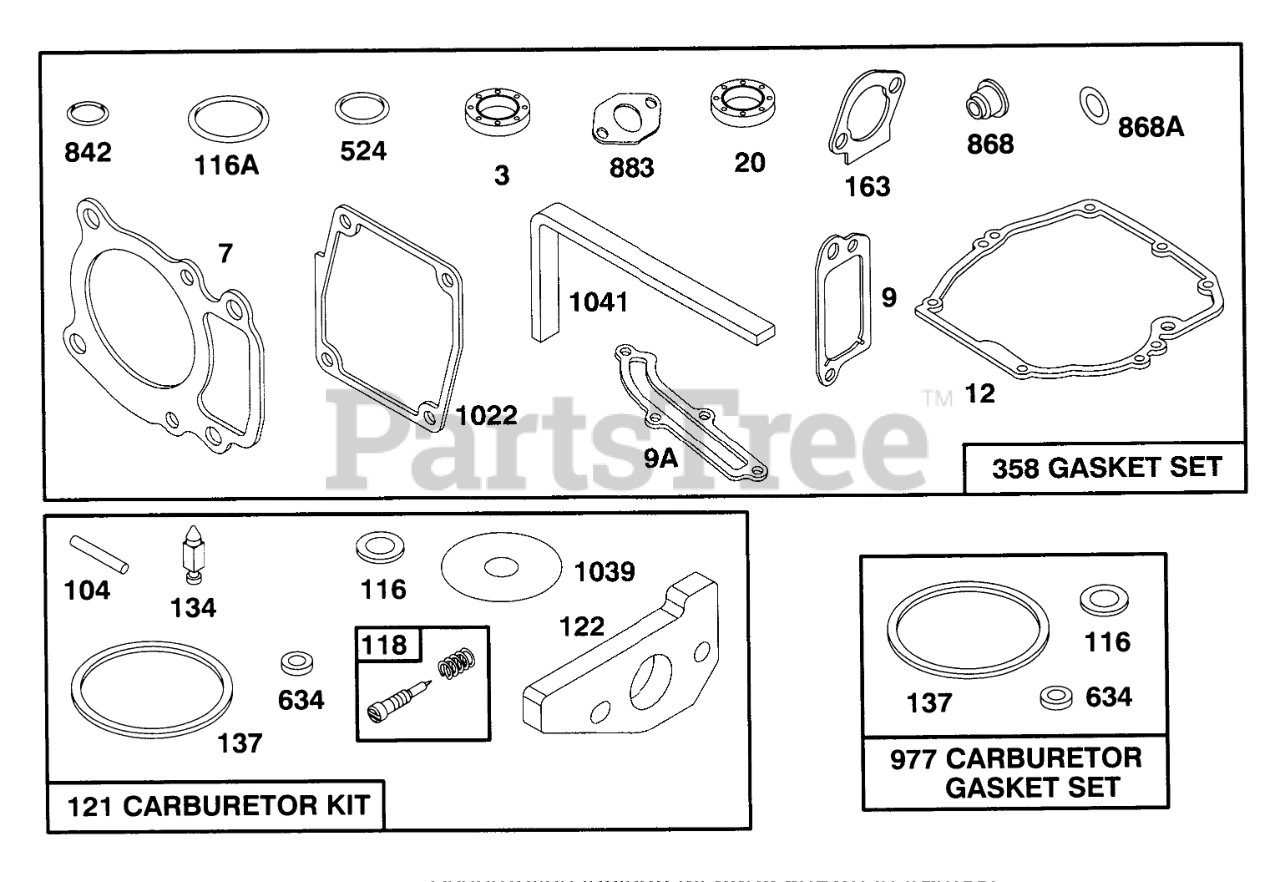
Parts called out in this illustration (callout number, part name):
3	SEAL - OIL
7	CYLINDER HEAD GASKET
9	BREATHER GASKET
9A	GASKET-BREATHER
12	ENGINE BASE GASKET
20	SEAL-OIL
104	FLOAT HINGE PIN
116	O RING SEAL
116A	SEALING GASKET
118	VALVE KIT - NEEDLE
121	CARBURATOR OVERHAUL KIT
122	ADAPTER ASSEMBLY
134	Valve-Inlet (Includes Seat)
137	FLOAT BOWL GASKET
163	AIR CLEANER GASKET
358	GASKET SET
524	O-RING
634	SEAL WASHER
842	O-RING
868	SealAssy-Valve
868A	Seal-Valve
883	EXHAUST GASKET
977	CARBURATOR GASKET SET
1022	ROCKER COVER GASKET
1039	FLOAT LIMITER
1041	SEAL - FOAM
